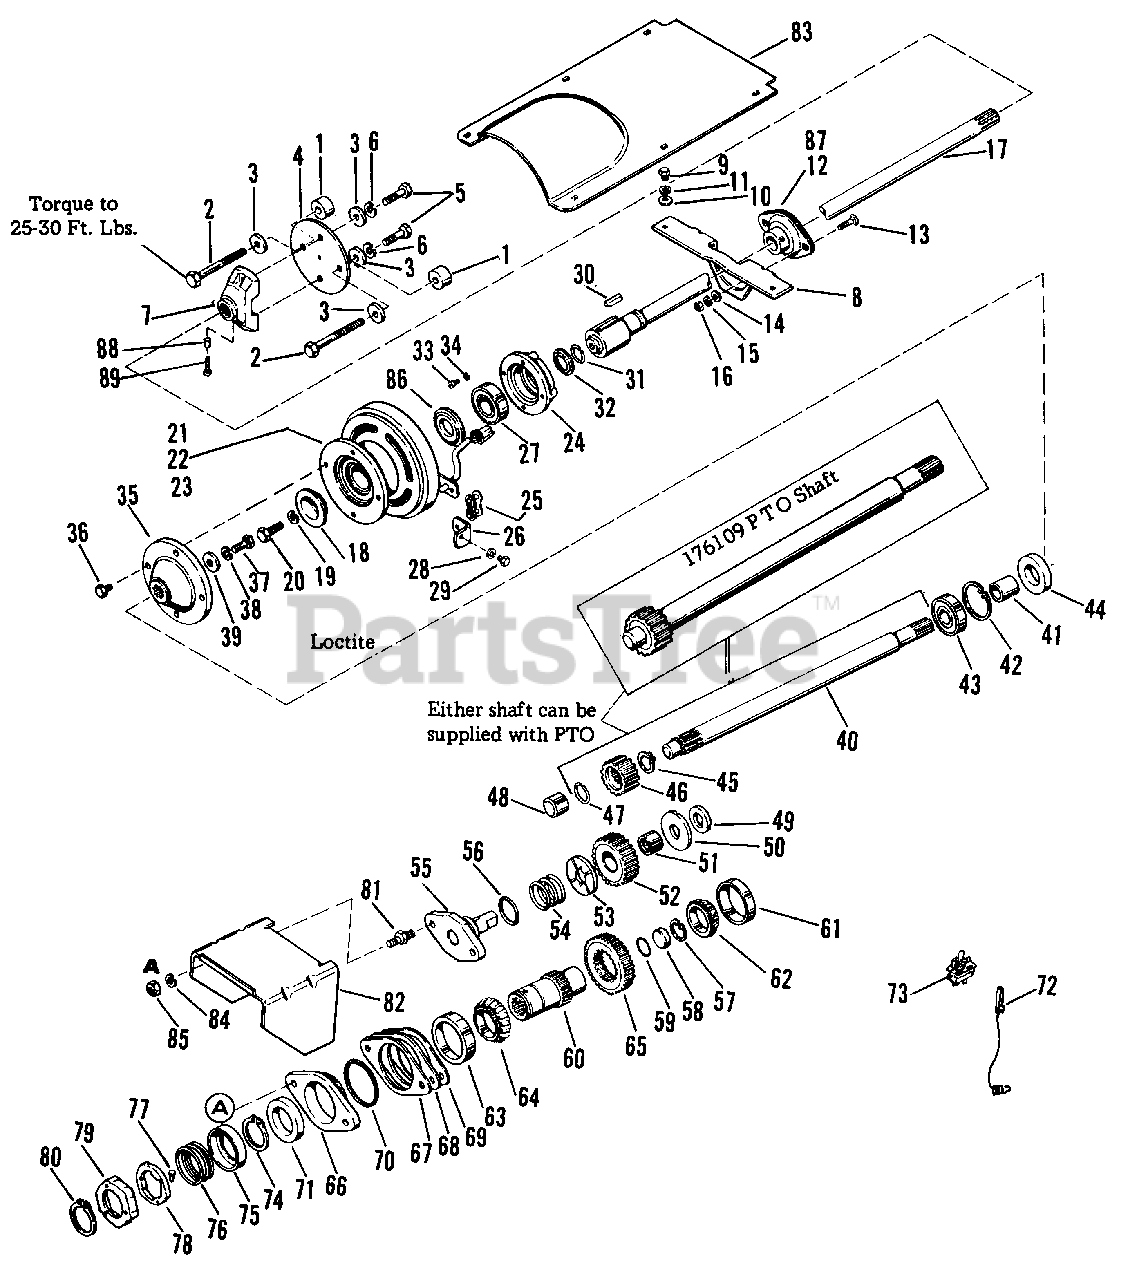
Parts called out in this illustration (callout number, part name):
2	Hex Capscrew, 3/8"-16 x 3-1/2" lg.
5	Hex Capscrew, 3/8"-16 x 1-1/4" lg.
6	Lock Washer, 3/8"
9	Hex Capscrew, 1/4"-20 x 5/8" lg.
10	Plain Washer, 3/16"
11	Lock Washer, 1/4"
13	Rd. Hd. Bolt, 5/16"-18 x 3/4" lg.
14	Plain Washer, 1/4"
15	Lock Washer, 5/16"
16	Hex Nut, 5/16"-18
17	Shaft Assembly
19	Lock Washer, 3/8"
20	Hex Capscrew, 3/8"-16 x 1-1/4" lg.
21	Electric Clutch
22	Field Assy. (For Service Only)
23	Armature Assy. (For Service Only)
24	Bearing Retainer
25	Connecting Link
26	Bracket Assembly
28	Lock Washer
29	Hex Capscrew
31	Retaining Ring
32	Retaining Collar
33	Lock Washer No. 10
34	Soc. Hd. Screw, No. 10-32 x 1/2" lg.
36	Hex Capscrew, 5/16"-18 x 1" lg.
37	Hex Capscrew, 3/8"-16 x 1" lg.
38	Lock Washer, 3/8"
40	P.T.O. Shaft
42	Retaining Ring
45	Retaining Ring
46	Gear 20 Tooth
47	Retaining Ring
50	Thrust Washer
51	Bearing
53	Thrust Washer
55	Cap Assembly
57	Retaining Ring
60	Drive Gear
61	Bearing Cone
62	Bearing Cup
63	Bearing Cone
64	Bearing Cup
65	Gear 36 Tooth
67	Shim .002
68	Shim .010
69	Shim .003
72	Jumper Wire
73	Toggle Switch
74	Retaining Ring
75	Inner Retainer
79	Outer Cover
80	Retaining Ring
83	Cover Top
84	Lock Washer, 3/8"
85	Hex Nut, 3/8"-16
87	Flangette Bearing
88	Plug, Nylon
89	Set Screw Cup Pt.
